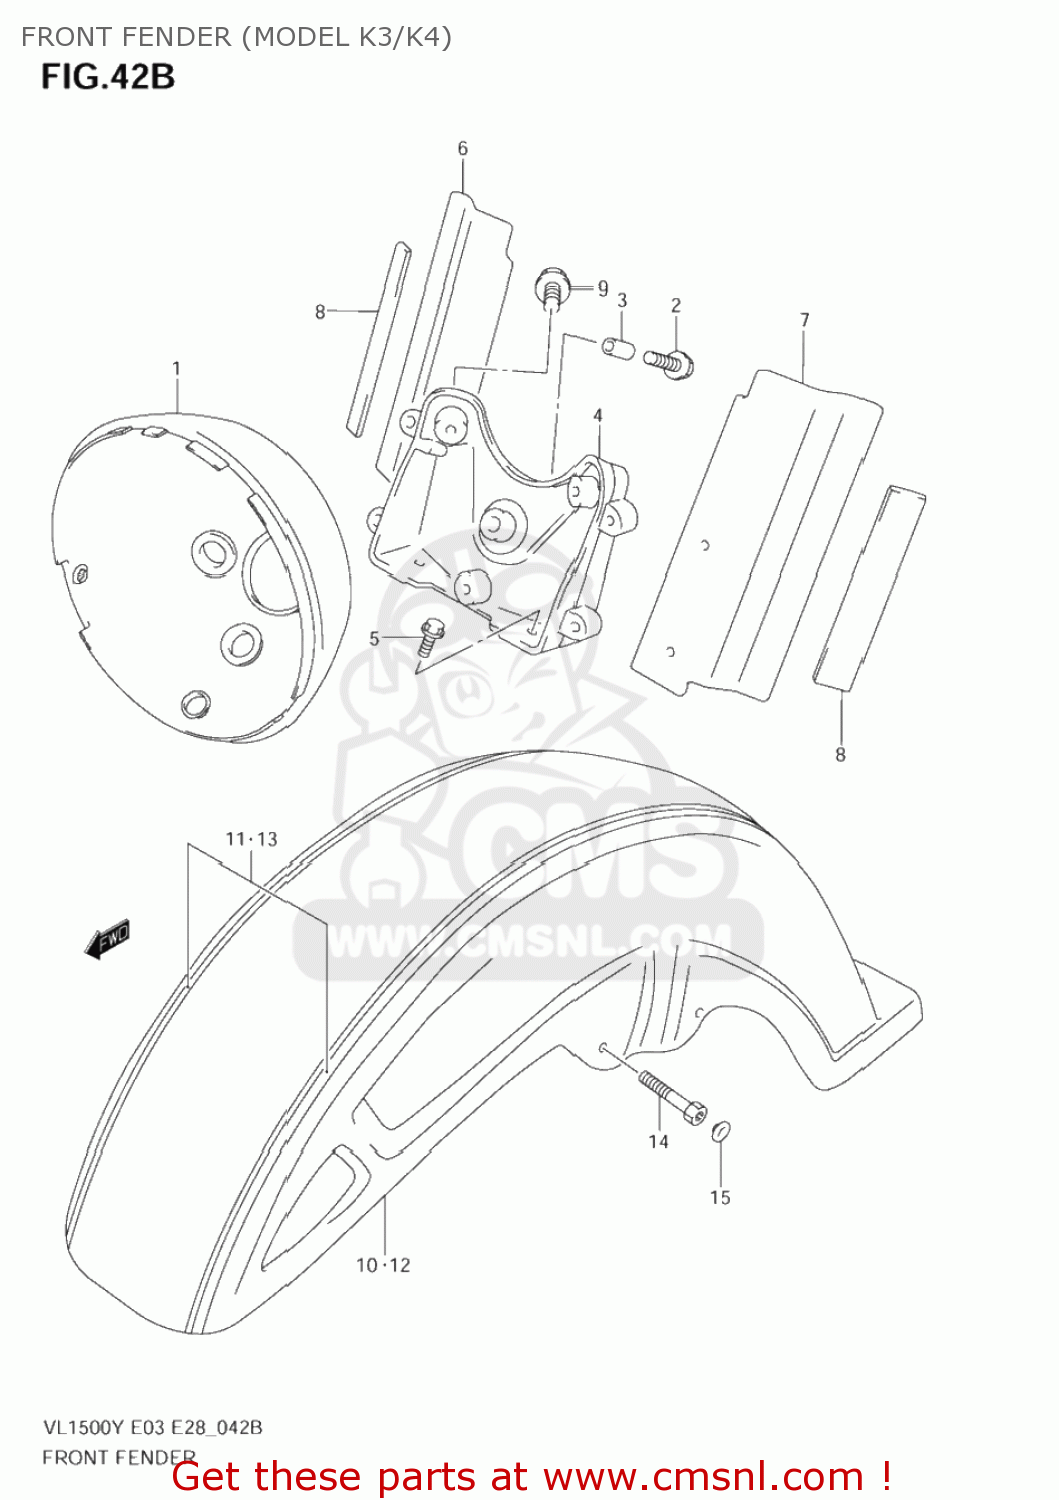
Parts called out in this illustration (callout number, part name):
1	HOUSING,HEADLAMP
2	BOLT(6X25)
3	SPACER(6.8X12X11)
4	BRACKET,HEADLAMP HOUSING
5	BOLT
6	PLATE,HEADLAMP BRACKET,R
7	PLATE,HEADLAMP BRACKET,L
8	PROTECTOR(170X95X3.0)
9	SCREW(6X12)
10	FENDER ASSY,FR
11	TAPE SET,FR FENDER
12	FENDER ASSY,FR
13	TAPE SET,FR FENDER
14	BOLT
15	CAP(OD:11)
